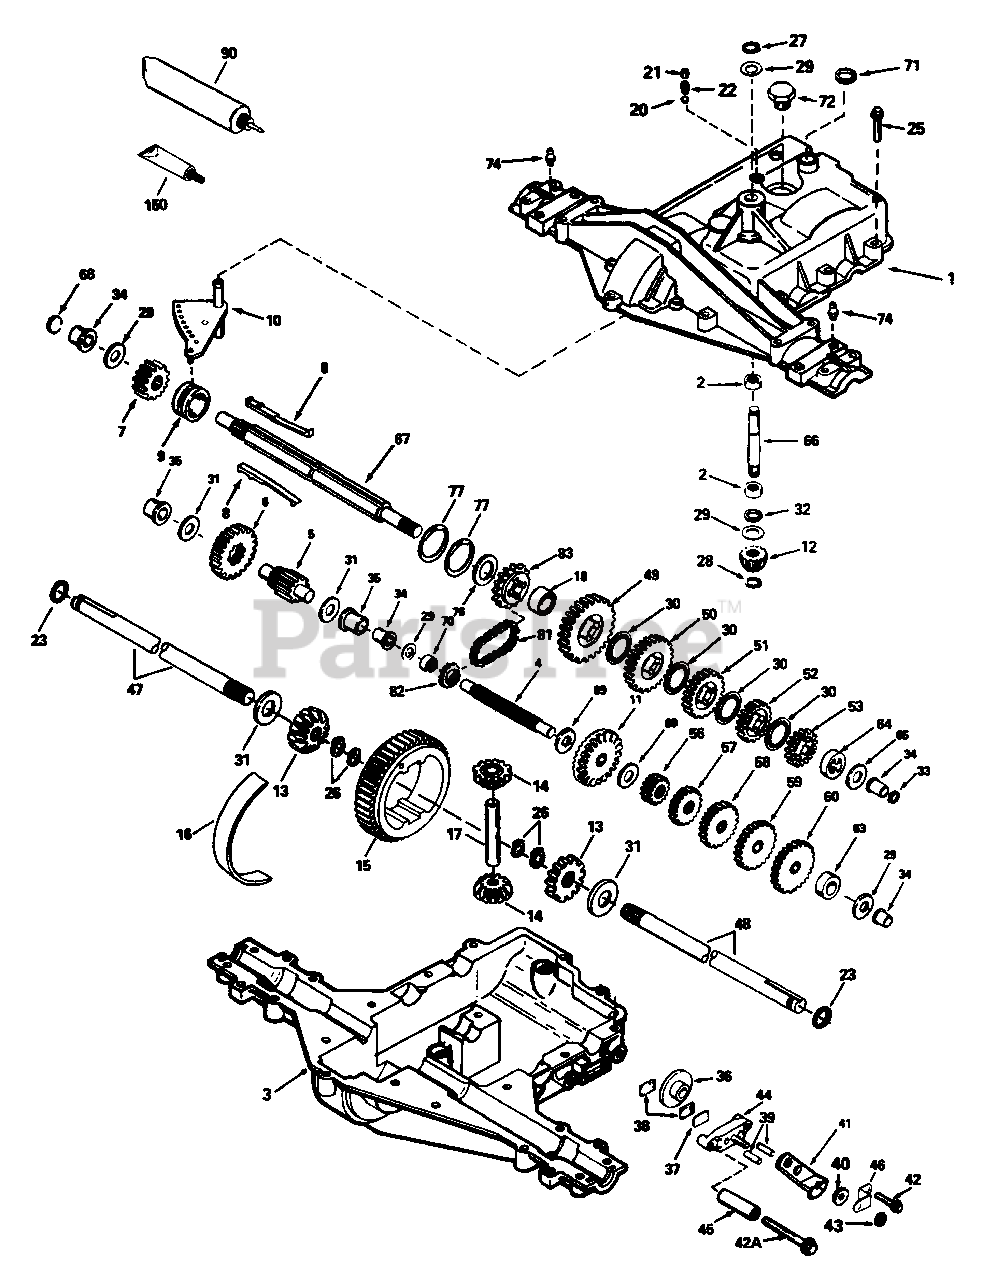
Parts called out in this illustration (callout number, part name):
1	COVER, Transaxle
2	BEARING, Needle
3	CASE, Transaxle
4	SHAFT, Counter
5	SHAFT & PINION ASSY., Output
6	GEAR, Output
7	Gear, Spur (15 teeth)
8	KEY, Shifter
9	COLLAR, Shifter
10	ROD & FORK ASSY., Shift
11	GEAR, Bevel (42 teeth)
12	BEVEL PINION, Input
13	GEAR, Bevel
14	GEAR, Bevel Pinion
15	GEAR, Ring
16	STRIP, Bearing
17	PIN, Drive
20	BALL, Steel (5/16" dia.)
21	SETSCREW, 3/8 16 x 3/8
23	RING, Seal
25	SCREW, Flanged Hex Hd., Threadforming, 1/4-20 x 1-1/4
26	RING, Retainer (Pkg. of 2)
27	RING, Retainer
28	RING, Retainer
29	WASHER, Thrust
30	WASHER, Thrust
33	SEAL, Square Cut
34	BUSHING, Flanged
35	BUSHING, Flanged
36	DISK, Brake
37	PLATE, Brake Pad
38	PAD, Brake
39	PIN, Dowel
40	WASHER, Flat
41	LEVER, Brake
42	SCREW, Flanged Hex Hd., Threadforming, 1/4-20 x 1-1/4
42A	SCREW, Flanged Hex Hd., Threadforming, 1/4-20 x 1-1/4
43	NUT, Lock, 5/16-24
44	HOLDER, Brake Pad
46	BRACKET, Brake Lever
47	AXLE (11-5/32" Long)
48	AXLE (16-27/32" Long)
49	GEAR, Spur (37 teeth)
50	GEAR, Spur (30 teeth)
51	GEAR, Spur (25 teeth)
52	GEAR, Spur (22 teeth)
53	GEAR, Spur (19 teeth)
56	GEAR, Spur (12 teeth)
57	GEAR, Spur (20 teeth)
58	GEAR, Spur (25 teeth)
59	GEAR, Spur (28 teeth)
60	GEAR, Spur (31 teeth)
65	WASHER, Thrust
66	SHAFT, Input
67	SHAFT, Brake (4-Keyed)
69	WASHER, Thrust
71	SEAL Square Cut
72	PLUG, Hex Hd., 9/16-18 Thread
74	FITTING, Lubrication
76	WASHER, Thrust
77	RING, Retaining (Pkg. of 2)
81	CHAIN, Roller (No. 41 chain, 22 Links)
82	SPROCKET (10 teeth)
83	SPROCKET (14 teeth)
90	GREASE (32 oz. Bottle Bentonite grease)
150	ADHESIVE (Loctite #515)
